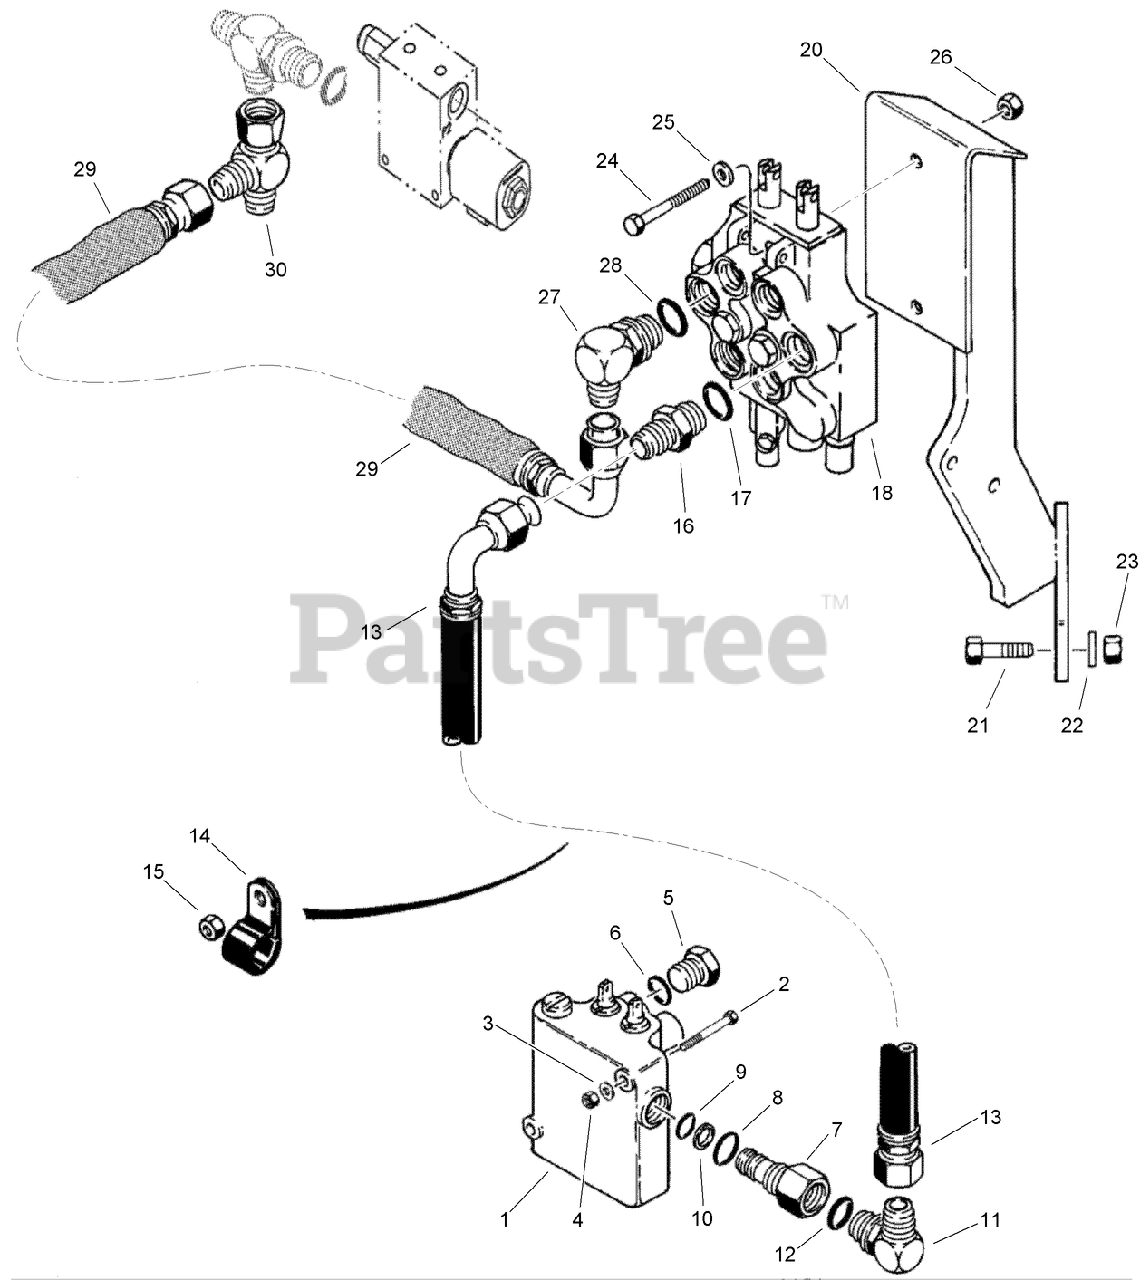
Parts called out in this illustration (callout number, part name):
1	HYD STEERING VALVE ASM
2	BOLT-1/4-20 x 2
3	WASHER-FLAT
4	NUT-Prev Trq 1/4 GRC PHC Direct
5	PLUG-Hex Hd, ORB 3/8
7	BODY - Adapter
8	O-RING
9	O-RING
10	RING - Backup
11	ELBOW - 90 Degree, 7/8-14 Flare x 3/4-16 inch Adj O-Ring Boss
12	O-RING
13	HOSE - 2135 mm (84 inch) Long, Steering and Attachment Lift Control Valve to Plow Control Valve
14	CLAMP - P-Type, 1 inch ID (attaches to lockout valve mounting bolt)
15	NUT-HEX
16	CONNECTOR-Str Thd 5/8, 37FL-ORB 5/8
17	O-RING
18	VALVE ASSEMBLY - Control, Plow Lift and Swing
20	BRACKET - Mounting, Plow Control Valve
21	SCREW-HH
23	NUT-HEX
24	BOLT - Hex, 5/16 NC x 2-3/4 inch
25	WASHER-FLAT
26	NUT-HEX
27	ELBOW-90 Adj 37FL 3/4 x 5/8 Tube
28	O-RING
29	HOSE - 457 mm (18 inch) Long, Plow Lift / Swing Control Valve to Tee
30	FITTING-TEE
